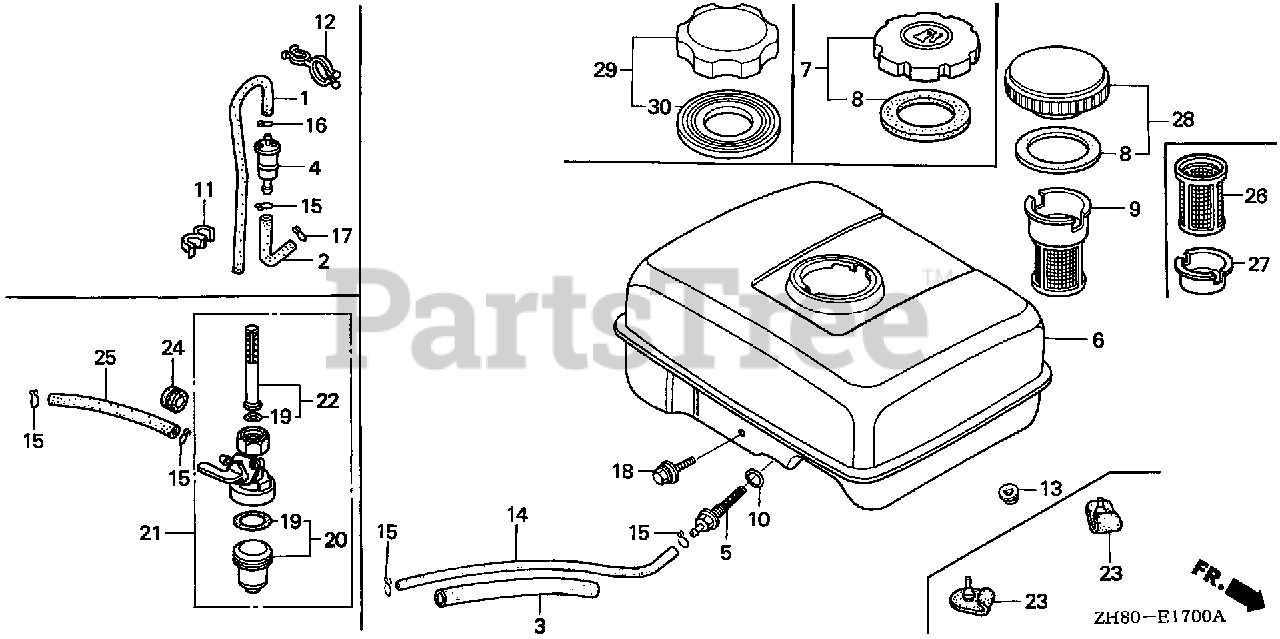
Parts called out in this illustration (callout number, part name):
3	RUBBER, SUPPORTER (107MM)
5	JOINT, FUEL TANK
6	TANK, FUEL *NH31* (MCKINLEY WHITE)
7	CAP, FUEL FILLER (BLACK)
8	GASKET, FUEL FILLER CAP (39X58X3)
10	O-RING (14MM) (ARAI)
10	O-RING (14MM) (NOK)
13	NUT, FLANGE (6MM)
14	BULK HOSE, FUEL (4.5X3000) (4.5X140)
15	CLIP, TUBE (B8)
18	BOLT, FLANGE (6X25)
28	CAP, FUEL FILLER (CHROME PLATED)
28	CAP, FUEL FILLER
